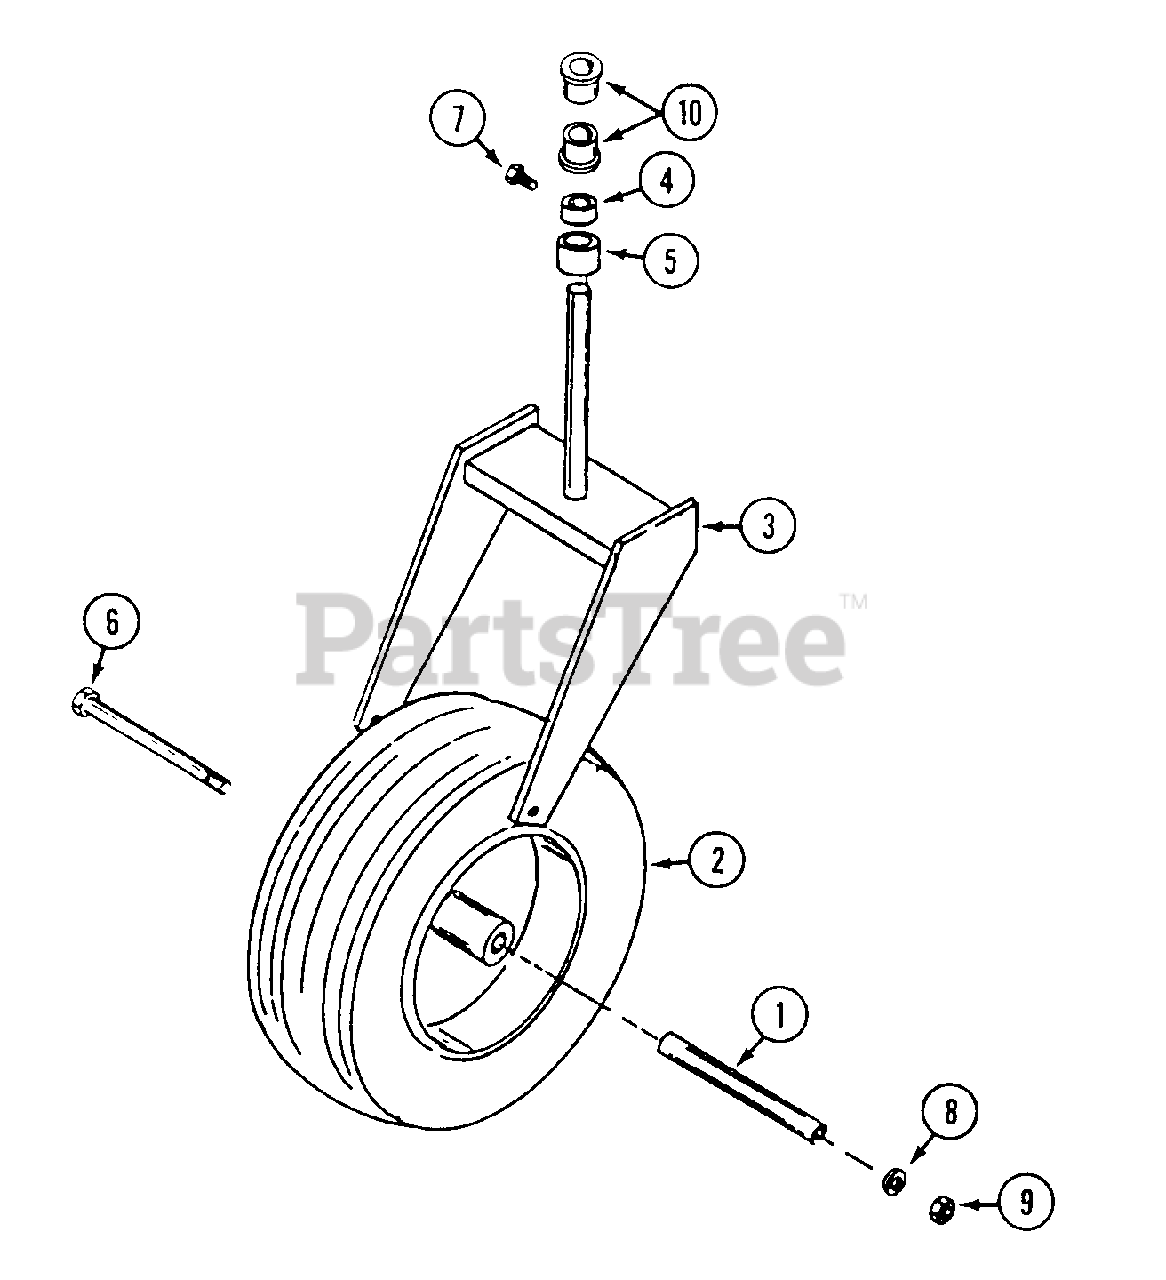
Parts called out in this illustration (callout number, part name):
2	WHEEL ASSEMBLY - tail
3	FORK - tail wheel
4	COLLAR - set 1"
5	SPACER - tail wheel fork
6	BOLT - 1/2" - 13 x 9-1/2"
7	SCREW -set 5/16" - 18 x 1/2" square head
8	LOCKWASHER - 1/2"
9	NUT - 1/2" - 13
10	BEARING - ball 1"
